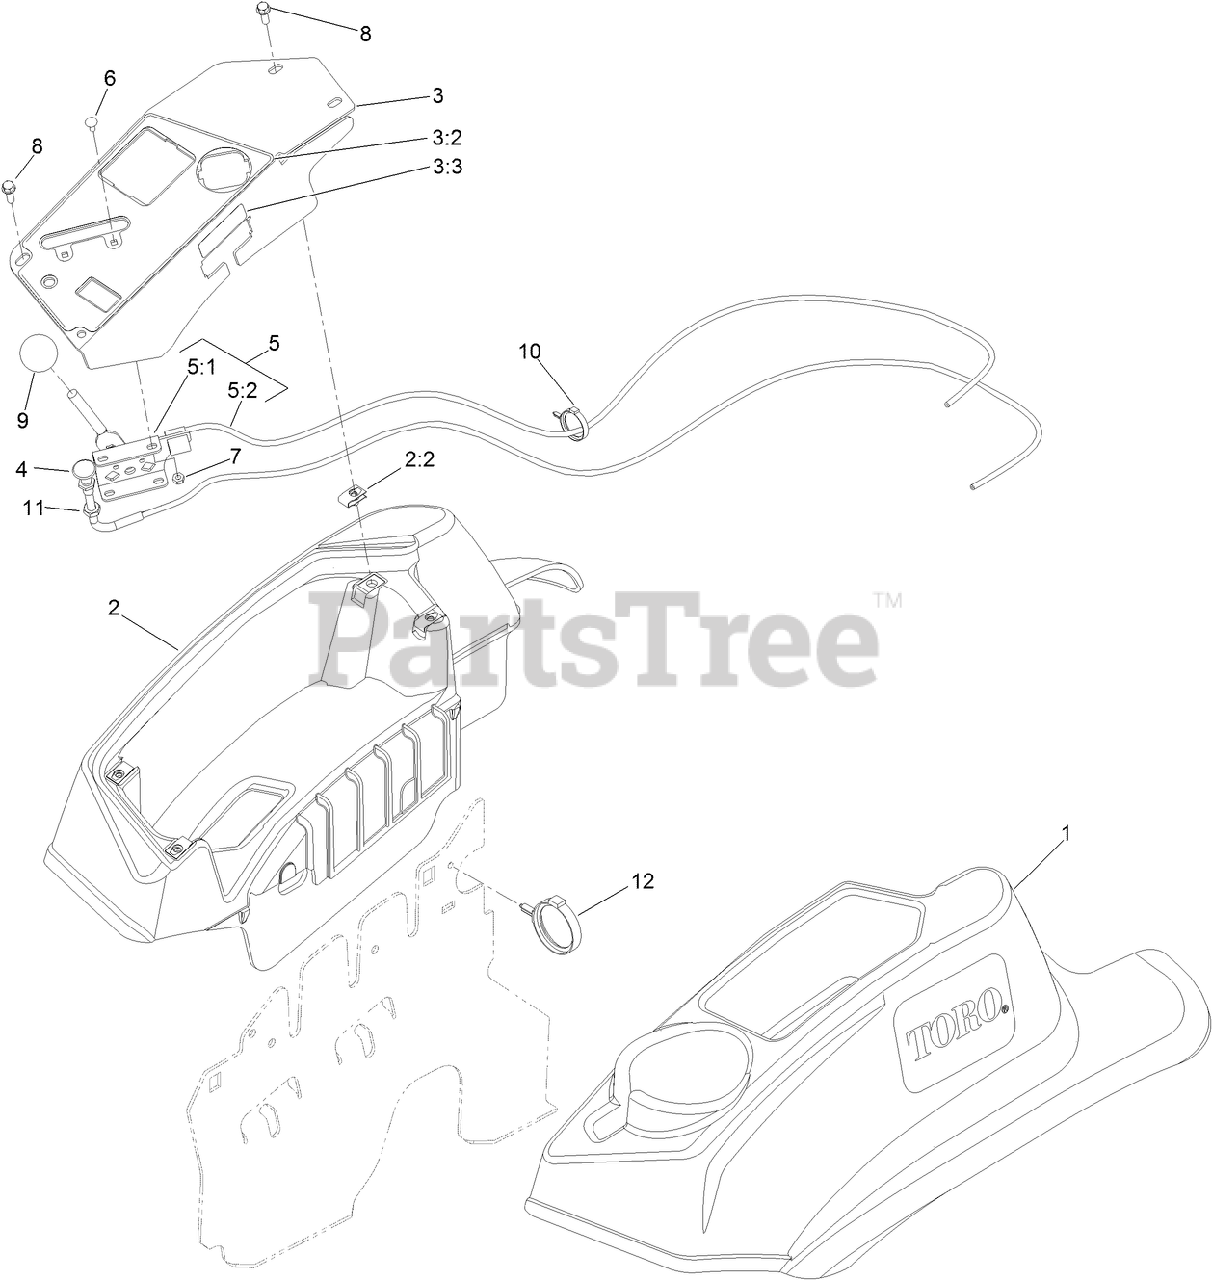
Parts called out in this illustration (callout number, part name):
1	CONSOLE-LH
2	RH CONSOLE ASM
3	CONTROL PANEL ASM
3:2	DECAL-CONTROL PANEL
3:3	DECAL-FUSES
4	CONTROL-CHOKE
5	THROTTLE CONTROL ASM
5:1	LEVER-THROTTLE
5:2	CABLE-THROTTLE
6	BOLT-CARR
7	NUT-LOCK, NI
8	SCREW-HWH
9	KNOB-BALL
10	CLAMP-HOSE
11	NUT-HJ
12	CLAMP-HARNESS
